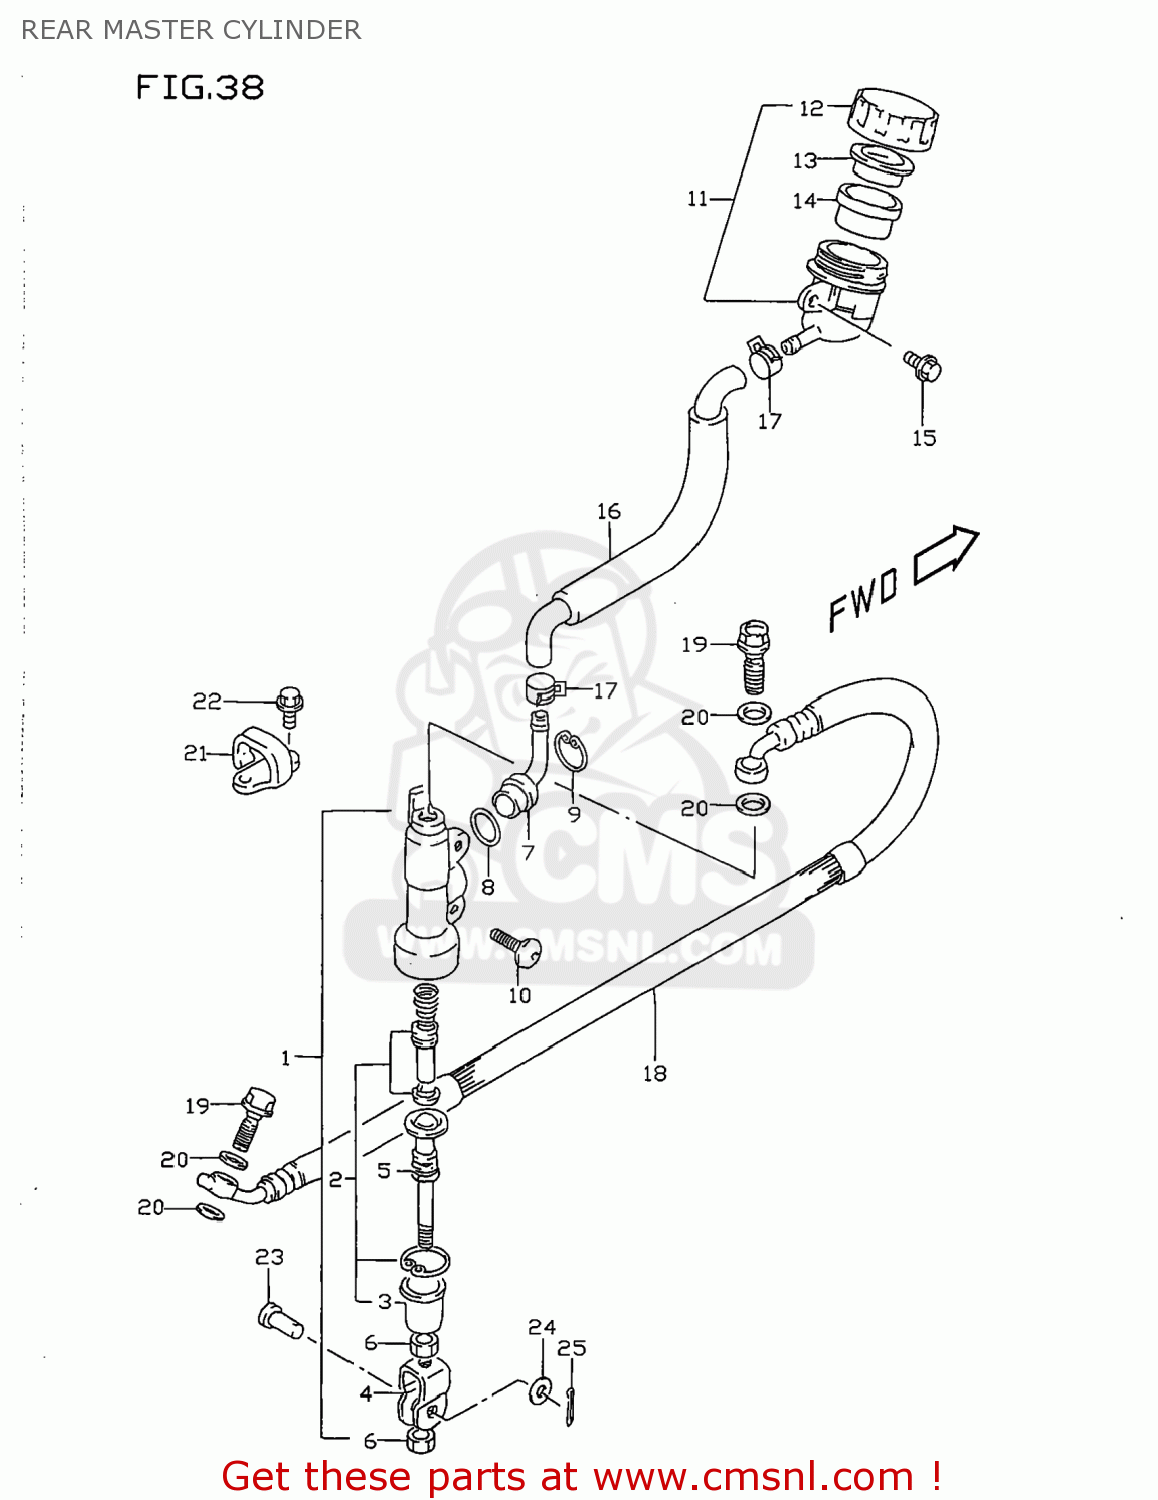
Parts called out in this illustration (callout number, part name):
1	CYLINDER ASSY,RR MASTER
2	PISTON/CUP SET
3	BOOT
4	YOKE
5	ROD,PUSH
6	NUT
7	CONNECTOR
8	O RING
9	CIRCLIP
10	SCREW(6X16)
11	TANK ASSY,RR BRAKE RESERVOIR
12	CAP
13	PLATE
14	DIAPHRAGM
15	BOLT
16	HOSE,RESERVOIR TANK
17	CLAMP,RESERVOIR HOSE
18	HOSE,RR BRAKE
19	BOLT UNION
20	WASHER(10X15X1.5)
21	GUIDE,RR BRAKE HOSE
22	SCREW
23	PIN(8X20)
24	WASHER(8.5X13X1.6)
25	PIN
